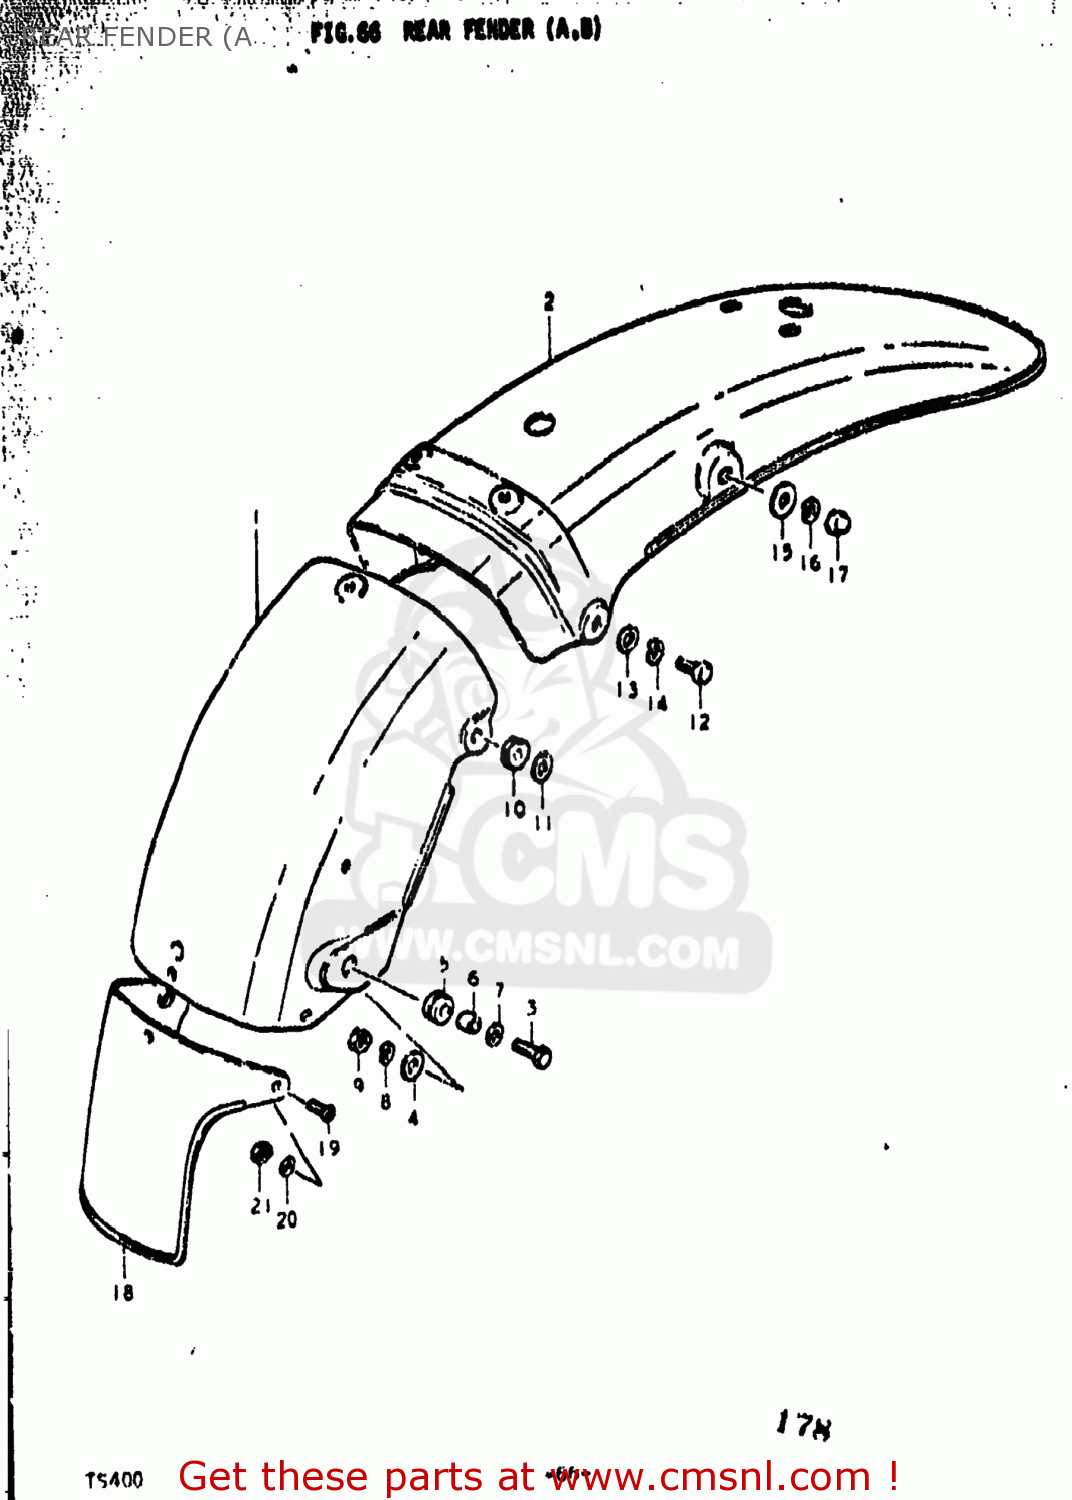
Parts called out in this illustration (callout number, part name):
1	FENDER,REAR
2	FENDER,REAR
3	BOLT
4	WASHER (6.5X20X1.2)
5	CUSHION
6	SPACER(6.1X9X7.5)
7	WASHER
8	LOCK WASHER
9	NUT
10	CUSHION
11	WASHER
12	BOLT
13	WASHER 6MM
14	LOCK WASHER
15	WASHER
16	LOCK WASHER
17	NUT
18	MUD GUARD,REAR FENDER
19	SCREW
20	WASHER
21	NUT
